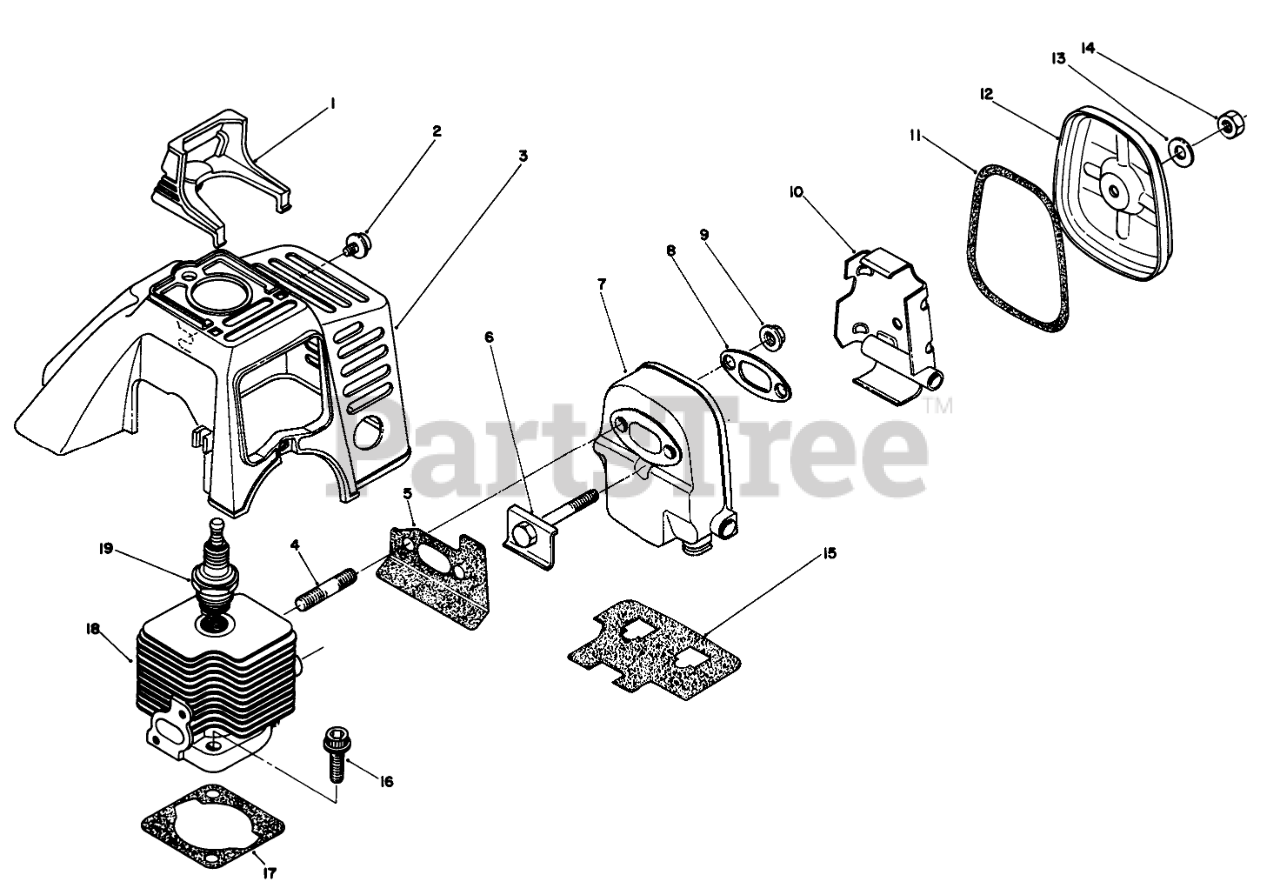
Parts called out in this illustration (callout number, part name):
1	SPARK PLUG GUARD
2	SCREW & WASHERE
3	Cover, Top
5	MUFFLER GASKET
7	BODY MUFFLER
8	PLATE
10	PLATE
11	GASKET
12	MUFFLER LID
13	GASKET
15	Gasket
16	FLANGE BOLT
17	CYL GASKET
18	CYLINDER
19	SPARK PLUG (NGK)
